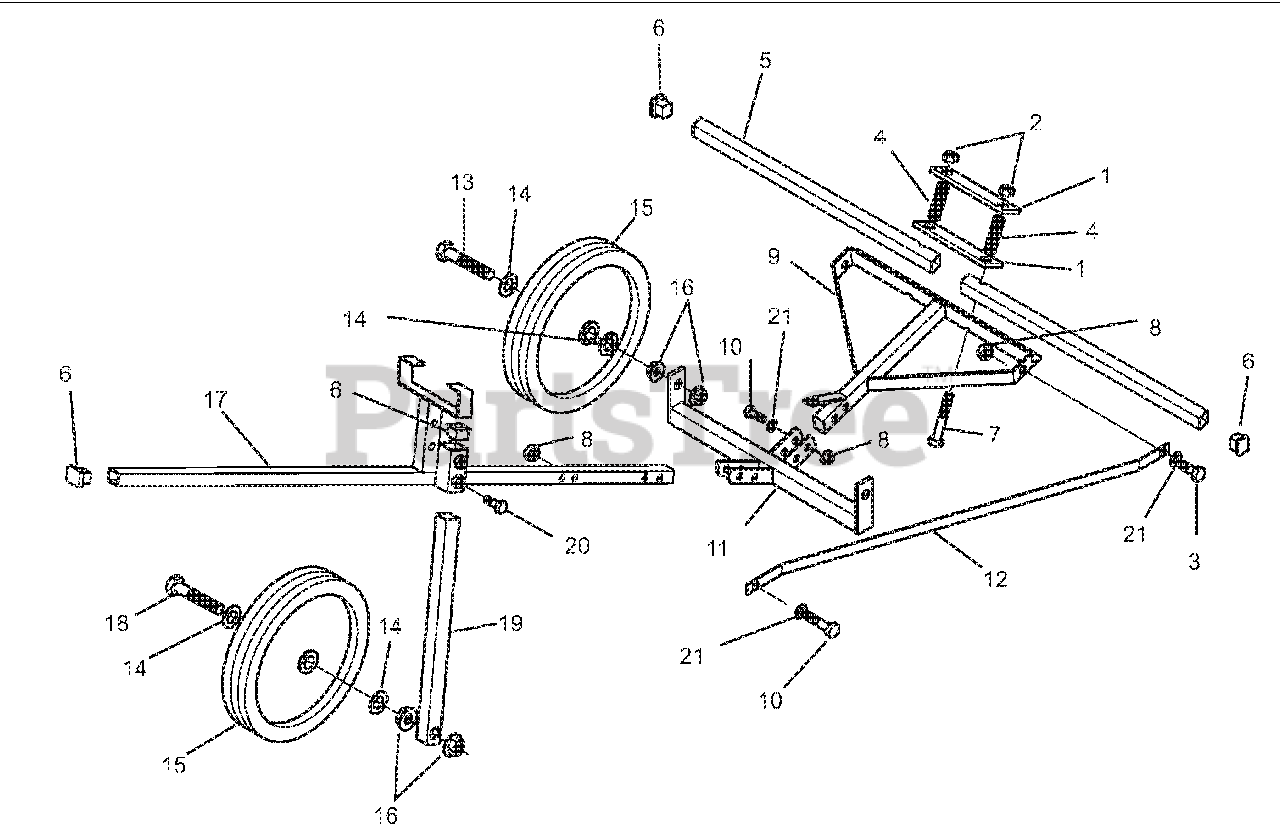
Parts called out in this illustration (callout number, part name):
1	Spring Strap
2	Nut, 3/8-16, Nyloc
3	Capscrew, 1/4-20 x 3/4, Hex
5	Boom Tube
6	Cap, 1" Square
7	Capscrew, 3/8-18 x 6, Hex G5
8	Nut, 1/4-20 Hex, Serrated Flanged CP
9	Boom Arm Tube Weldment
10	Capscrew, 1/4-20 x 1-3/4, Hex G5
11	Axle Weldment
13	Capscrew, 1/2-13 x 3-1/2 Hex
14	Washer, 1/2 Flat USS ZP
15	Wheel and Tire Assembly
16	Nut, 1/2-13, Serrated Flanged Hex
17	Center Handle
18	Capscrew, 1/2-13 x 4, Hex
19	Leg Tube
20	Bolt, 3/8-16 x 1, Hex
21	Washer, 1/4, Flat USS ZP
